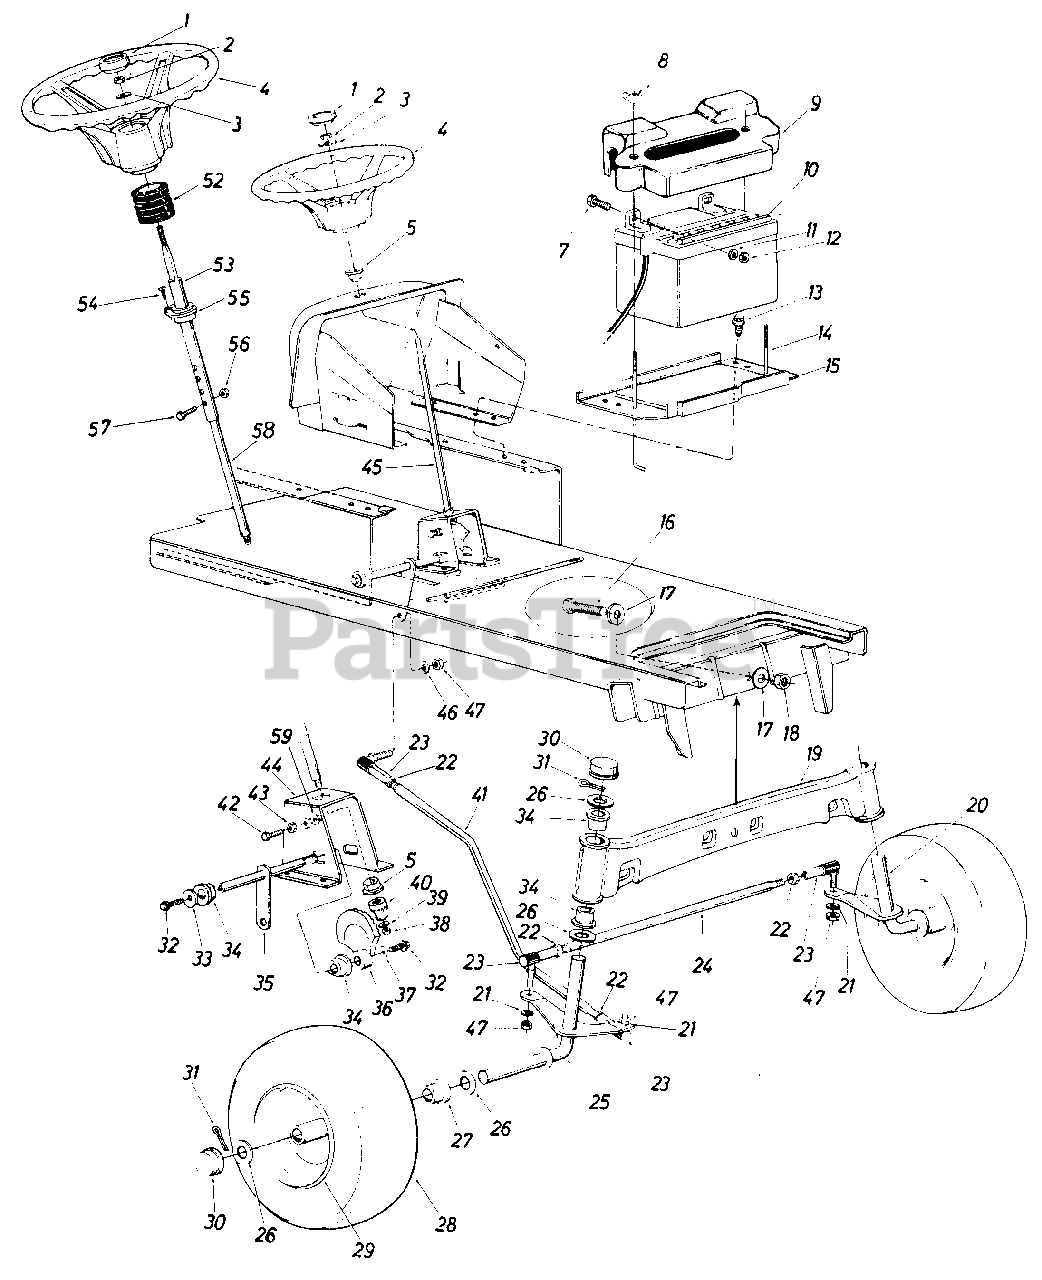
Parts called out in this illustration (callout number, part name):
1	Steering Wheel Cap
2	Hex Cent. L-Nut 5/16-24 Thd.
3	Bell-Wash. 5/16" I.D. x .87" O.D. x .060
4	Steering Wheel
5	Plastic Hex Bearing 5/8" I.D.
7	Hex Bolt 1/4-20 x .62" Lg.
8	Wing Nut Plastic 1/4-20 Thd.
9	Batery Cover
10	12-V Batery
11	L-Wash. 1/4" I.D.
12	Hex Nut 1/4-20 Thd.
13	Hex Thd. Rolling Scr. 1/4-20 x .50" Lg.
14	Batery Hold Down Rod
15	Batery Plate
16	Hex Bolt 5/8-18 x 2.5" Lg.
17	Flat Wash. .66" I.D. x 2.25" O.D. x .17
18	Hex Cent. L-Nut 5/8-18 Thd.
19	Front Pivot Bar Ass'y.
20	Front Axle Ass'y. L.H.
21	L-Wash. 3/8" I.D.
22	Hex Jam Nut 3/8-24 Thd.
23	Ball Joint Ass'y.
24	Tie Rod
25	Front Axle Ass'y.R.H.
26	Fl-Wash. .780 I.D. x 1.59 O.D.
27	Flange Bearing
28	Front Wheel Ass'y. Comp.
29	Front Wheel Rim Only
30	Dust Cover
31	Coter Pin 5/32" Dia. x 1.00" Lg.*
32	Hex Bolt 3/8-24 x .75" Lg. Grade 5
33	Fl-Wash. 3/8 I.D. x 1.25 O.D. x .090
34	Flange Double "D" Brg. .753 I.D.
35	Steering Arm Shaft Ass'y.
36	Side Gear-Steering
37	Bell-Wash. 3/8" I.D.
38	Hex Cent. L-Nut 5/16-24 Thd.
39	Fl-Wash. 5/16" I.D. x .62 O.D. x .059
40	Pinion Gear-Steering
41	Drag Link
42	Hex Cap Scr. 3/8-16 x 1.25" Lg.
43	Hex Nut 3/8-16 Thd.
44	Steering Gear Sup. Ass'y.
45	Steering Shaft
46	L-Wash. 3/8" I.D.
47	Hex Nut 3/8-24 Thd.
52	Steering Bellow
53	Upper Steering Shaft
54	Oval Hd. Cr.Sunk Scr. #10 x 5/8" Lg.
55	Fl-Bearing .89" I.D. x 1.36" O.D.
56	Hex L-Nut 1/4-20 Thd.
57	Hex Bolt 1/4-20 x 1.25" Lg.
58	Lower Steering Shaft
59	Nylon Cap
